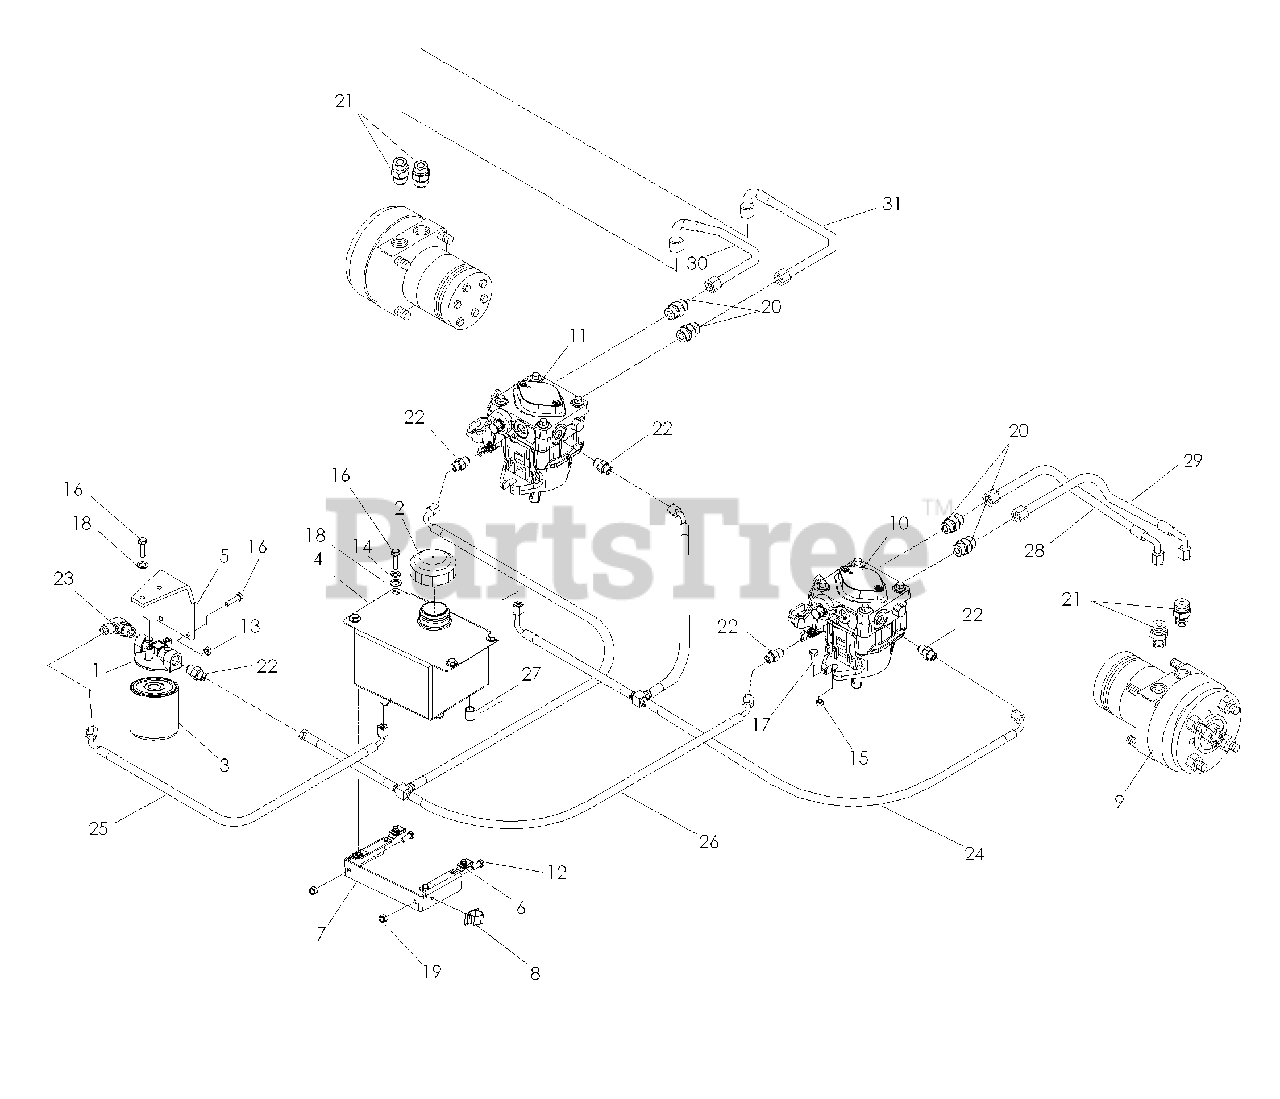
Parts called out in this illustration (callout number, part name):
1	FILTER HEAD
2	CAP HYDRO TANK
5	FILTER BRACKET
6	RETAINER 1/4-20 U-TYPE
7	TANK MOUNT
8	WIRE CLIP PUSH-MOUNT
9	TI15 WHEEL MOTOR
10	PUMP 10cc W/FAN LEFT
11	PUMP 10cc W/FAN RIGHT
12	HCS 5/16-18 x 3/4
13	NUT 1/4-20 HEX NYLOC
14	WASHER, 1/4 SPLIT LOCK
15	NUT 3/8-16 HEX CTR LK
16	HCS 1/4-20 x 3/4
17	HCS 3/8-16 x 1 WHIZLK
18	WASHER 1/4 FLAT
19	NUT 5/16-18 HEX NYLOC
20	FITTING STRAIGHT
21	FITTING STRAIGHT
22	FITTING STRAIGHT
23	FITTING ELBOW
24	"T" ASSEM RETURN
26	"T" ASSEM SUPPLY
28	HYDRAULIC LINE
29	HYDRAULIC LINE
30	HYDRAULIC LINE
31	HYDRAULIC LINE
